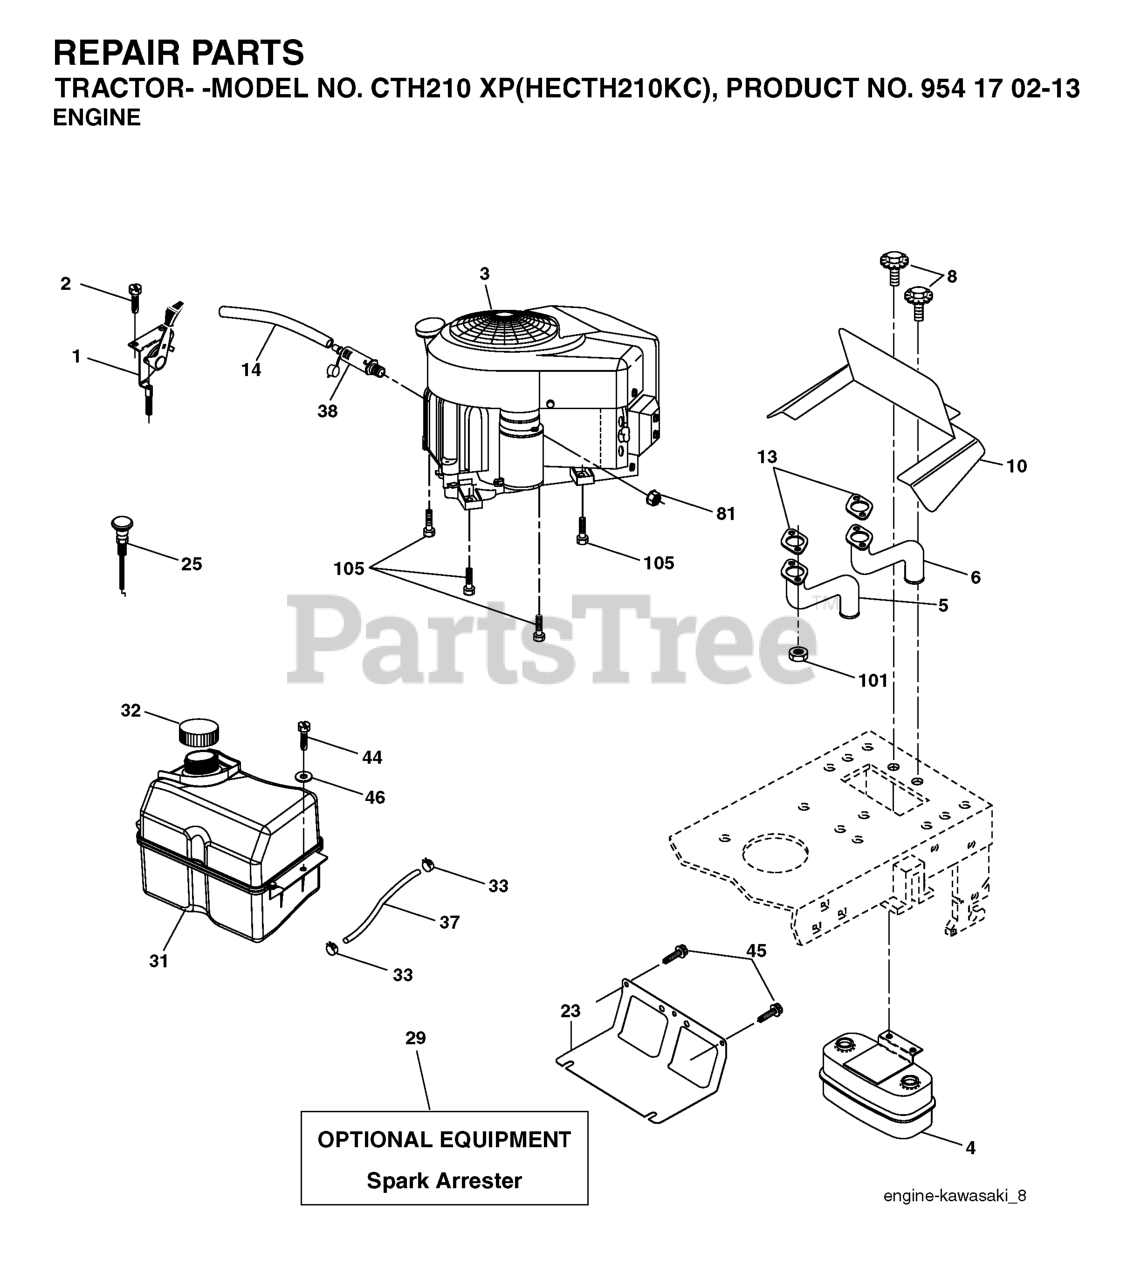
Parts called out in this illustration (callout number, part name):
2	SCREW
4	MUFFLER.TWIN.CYL.LOW.TONE
5	TUBE EXHAUST LH
6	EXHAUST.TUBE.RH.KAWA
8	BOLT.5/16-18UNCX3/4 W/SEMS.BLK
10	RP SHIELD HEAT MUFFLER
14	TUBE, DRAIN OIL ASM.
23	SHIELD.BROWNING.DBR.GUARD
25	CONTROL, CHOKE, 37", PUSH
29	KIT.SPARK ARRESTOR 794945 B&S
31	TANK FUEL
32	FUEL CAP
33	HOSE CLAMP
37	LINE.FUEL.20
44	SCREW HEXWSHR 1/4-20X3/4
45	SCREW, 3/8-16X3/4
81	NUT
101	NUT.HEX.FLANGE.TOPLOCK
105	SCREW 3/8-16X1
